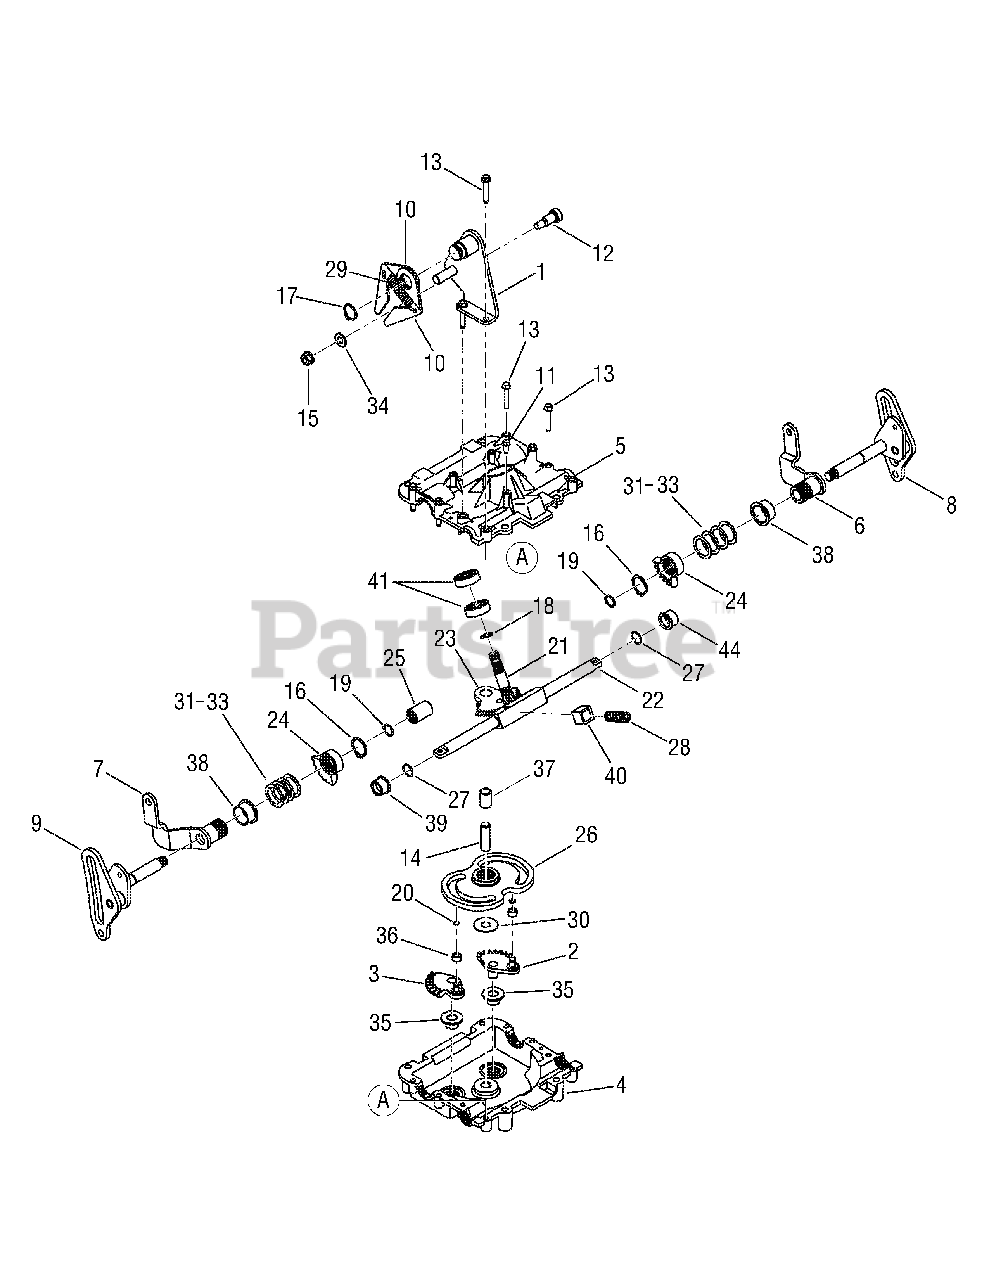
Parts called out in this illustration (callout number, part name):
1	Bracket, Steering Box Return
2	Gear, Bevel LH
3	Gear, Bevel RH
4	Housing, Steering Lower
5	Housing, Steering Upper
6	Arm, Hydro LH
7	Arm, Hydro RH
8	Cam, Hydro LH
9	Cam, Hydro RH
10	Arm, Neutral
11	Screw, Hex Wash Hd. Tapp, 1/4-20 x .5
12	Screw, Shoulder, .497 x .75 : 3/8-16
13	Screw, Hex Wash Hd. Tapp, 1/4-20 x 1.5
14	Shaft, Steering
15	Nut, Hex Flange Lock, 3/8-16 Gr5
16	Ring, Snap, 1.0 Dia. Shaft
17	Ring, External Retaining, .875 Shaft
18	Ring, Retaining, .56 Dia. Shaft
19	Ring, Retaining, .56 Dia. Shaft
20	Ring, Retaining, .31125 Dia. Shaft
21	Gear, Pinion, 7T
22	Gear, Synchro Rack
23	Gear, Steering, 17T
24	Gear, Steering, 26T
25	Tube, Coupler
26	Cam, Hydro Steering
27	O-Ring, .625 x .07
28	Spring, Compression, .531 x 1.25
29	Spring, Extension, .56 x 2.31 x .105
30	Washer, Flat, .508 x 1.32 x .04
31	Washer, Flat, 1.015 x 1.375 x .005
32	Washer, Flat, 1.015 x 1.375 x .010
33	Washer, Flat, 1.015 x 1.375 x .015
34	Washer, Thrust, .375 x .812 x .06
35	Bearing, Flange, .5 x .7
36	Bearing, Sleeve, .437 x .3425
37	Bearing, Sleeve, .623 x .5025 x .25
38	Bearing, Sleeve, 1.2 x 1.0
39	Bearing, Flange, .625 x .875
40	Bearing, Caster Rack
41	Bearing, Ball, .5625 x 1.375 x .4375
